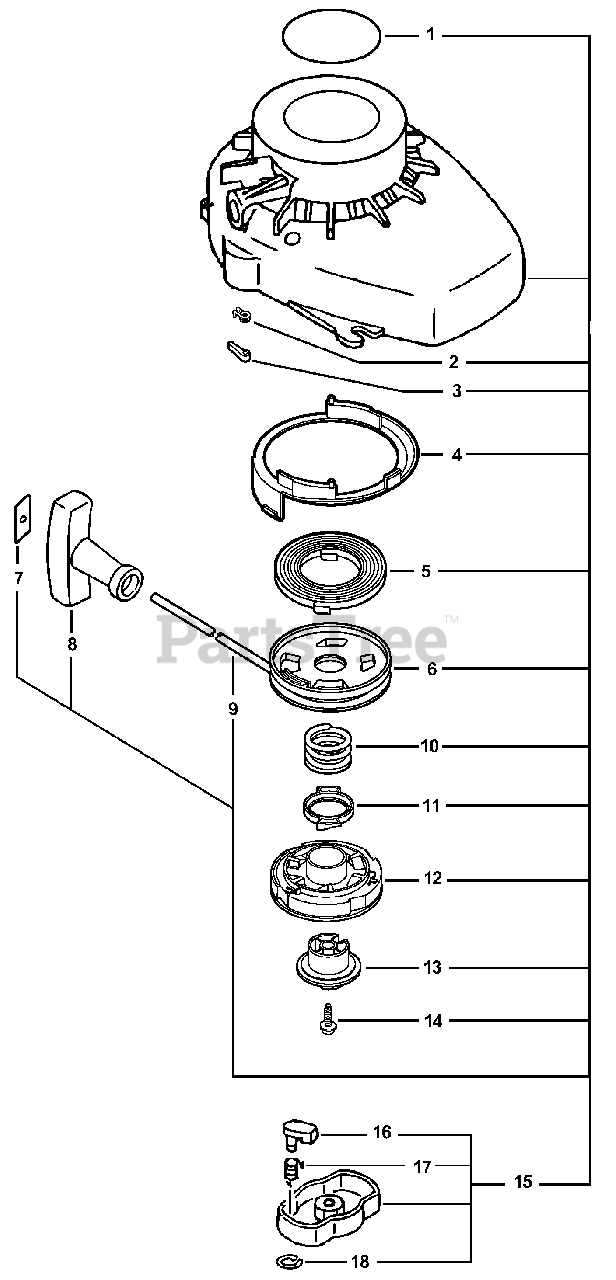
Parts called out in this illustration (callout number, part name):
1	LABEL
2	SPRING, PAWL RETURN
3	PAWL, STARTER
4	CASE, STARTER
5	SPRING, REWIND
6	REEL, ROPE
7	ROPE, STARTER - 3X800
8	GRIP, STARTER
9	RETAINER, ROPE
10	SPRING, RETURN
12	SPRING ASSY
13	PLATE, CAM
15	STARTER PAWL ASSY
16	PAWL, STARTER
17	SPRING, RETURN
18	RING, RETAINING - 4
